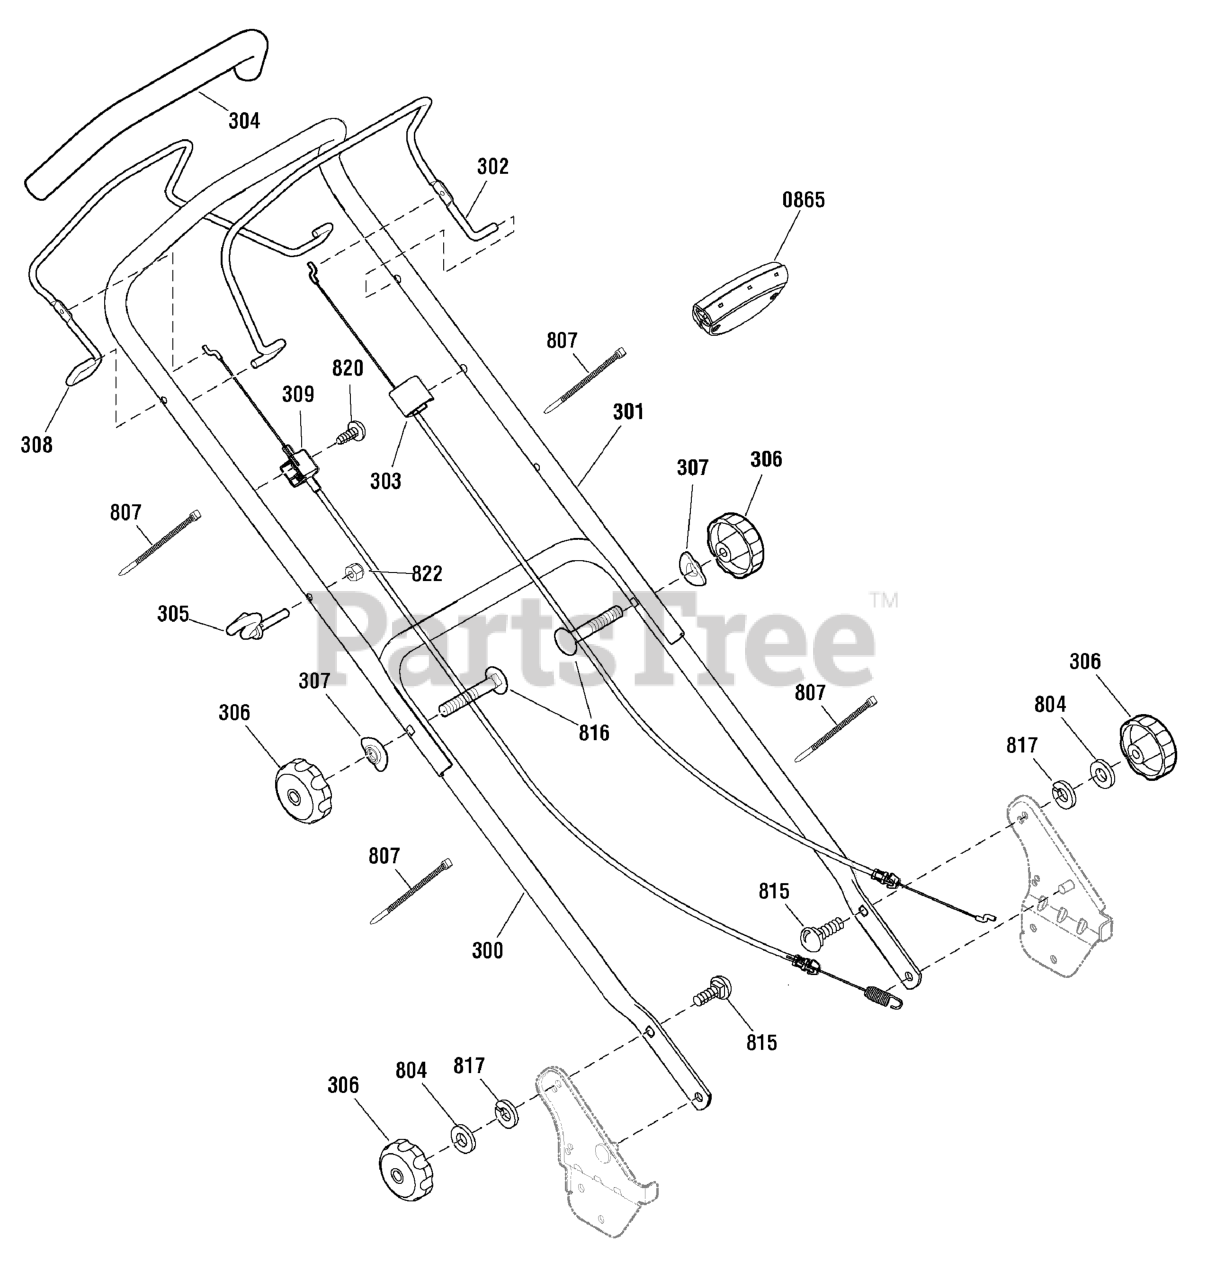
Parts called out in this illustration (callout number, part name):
300	HANDLE, Lower
301	HANDLE, Upper
302	LEVER, Engine Stop
303	CABLE, Engine Stop
304	TUBING, Foam
305	GUIDE, Rope
306	KNOB, 5/16-18
307	WASHER, Formed
308	LEVER, Drive
309	CABLE ASSEMBLY, Drive
804	WASHER, 5/8
807	CABLE TIE
815	BOLT, Carriage, 5/16-18 x 1-1/8
816	BOLT, Carriage, 5/16-18 x 2
817	WASHER, Lock
820	SCREW, Tap, #10 x 1-1/4
822	NUT, Hex, 1/4-20
865	SERVICE EXPERT
